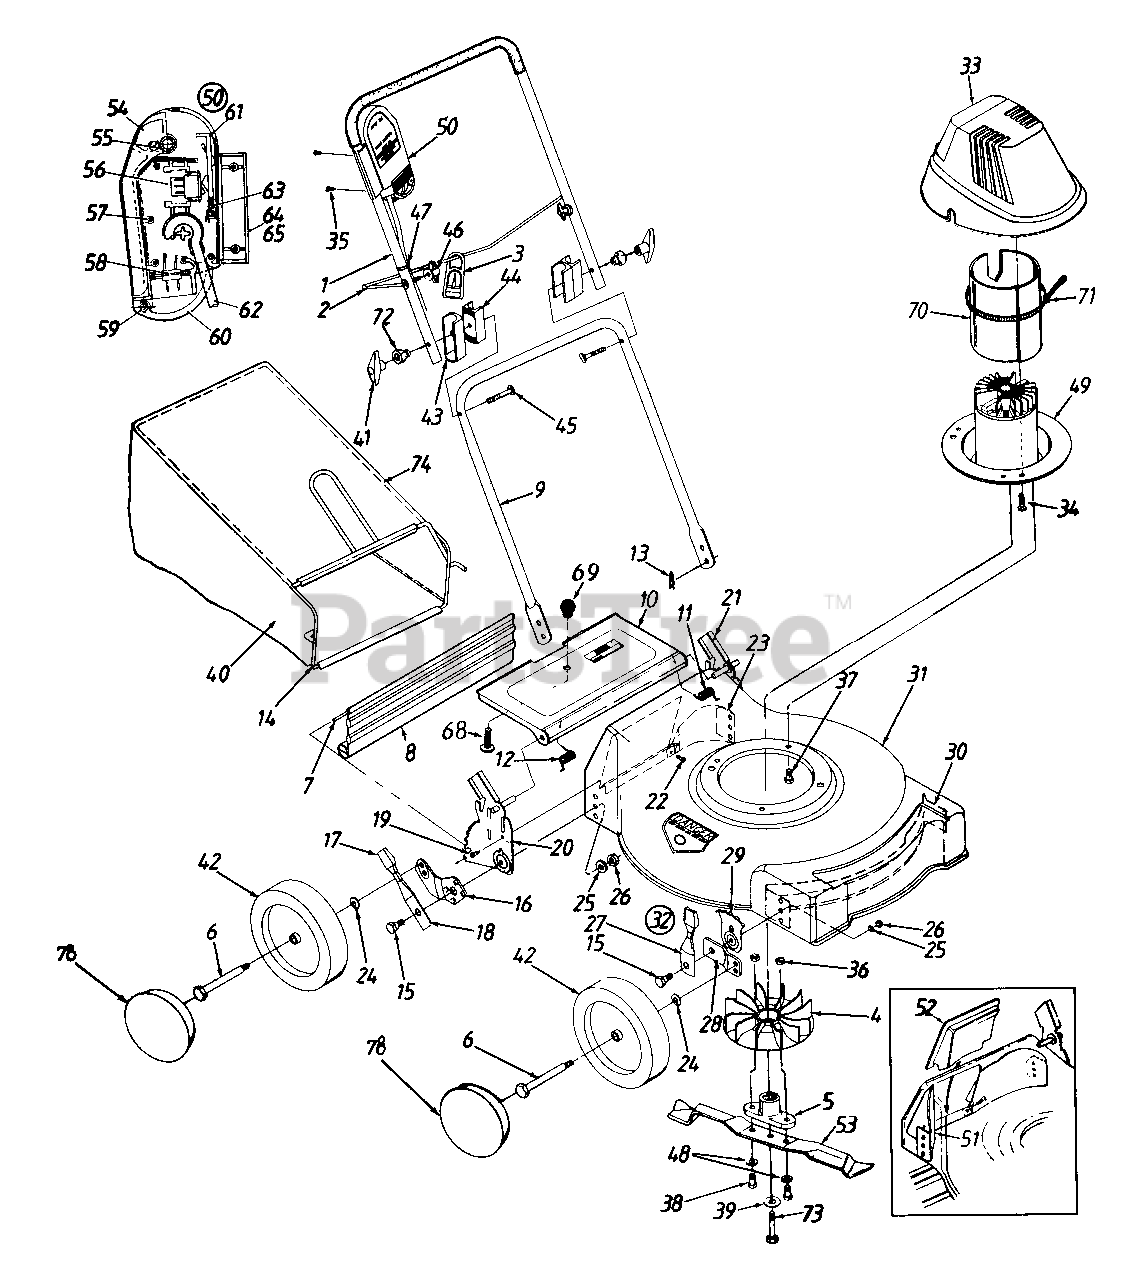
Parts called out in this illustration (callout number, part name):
3	Strain Relief - Cord
5	Blade Adapter
6	Axle Bolt
7	Rear Flap Wire
8	Rear Flap
9	Lower Handle
12	Door Spring - R.H.
13	Hairpin Clip
16	Pivot Bar - R.H.
17	Spring Lever Knob
18	Spring Lever
19	Hex L-Wash. Hd. AB-Tap Scr. 1/4 x .62" Lg.
20	Handle Brkt. Ass'y. - R.H.
21	Handle Brkt. Ass'y. - L.H.
22	Torx. Mach. AB - Tap Scr. 1/4 x .62" Lg.
23	Rear Baffle
24	Bell-Wash. .38" I.D. x .88" O.D.
25	Bell-Wash. .39" I.D. x 1.38" O.D.
26	Hex Nut 3/8-16 Thd.
27	Spring lever Ass'y. w/Knob
29	Height Adj. Plate
33	Motor Cover
34	Scr. #10-16 x .75" Lg.
35	Self-Tap. Scr. #7 x 1" Lg.
36	Hex Nut 3/8-24 Thd.
37	Hex L-Wash. TT-Tap Scr. 3/8-16 x .75" Lg.
38	Hex Bolt 3/8-24 x 1.25" Lg.
39	Bell-Wash. .396" I.D. x 1.14"
40	Grass Bag
41	Plastic Knob
42	Wheel Ass'y Comp.
43	Upper Handle Insulator
44	Lower Handle Insulator
45	Carriage Bolt 5/16-18 x 3" Lg
46	Wing Nut 1/4-20 Thd.
47	Cable Tie
48	Bell-Wash 3/8" I D
49	Motor, Cord & Switch Ass'y.
50	Cord & Switch Ass'y. Comp
53	19" Mulching Blade
54	Handle - Switch Actuator
55	Spring - Switch Handle
56	Switch
57	Screw #6-32 x 5" Lg.
58	Plug Ass'y
59	Retainer Plug Spring
60	Retainer Plug
62	Cord Ass'y.
63	Spring Latch
64	Housing - Upper Half
68	Truss Scr. #10-24 x .38" Lg
70	Insulator
71	Cable Tie
72	Insulator Knob
73	Hex Bolt 3/8-24 x 2 5" Lg
